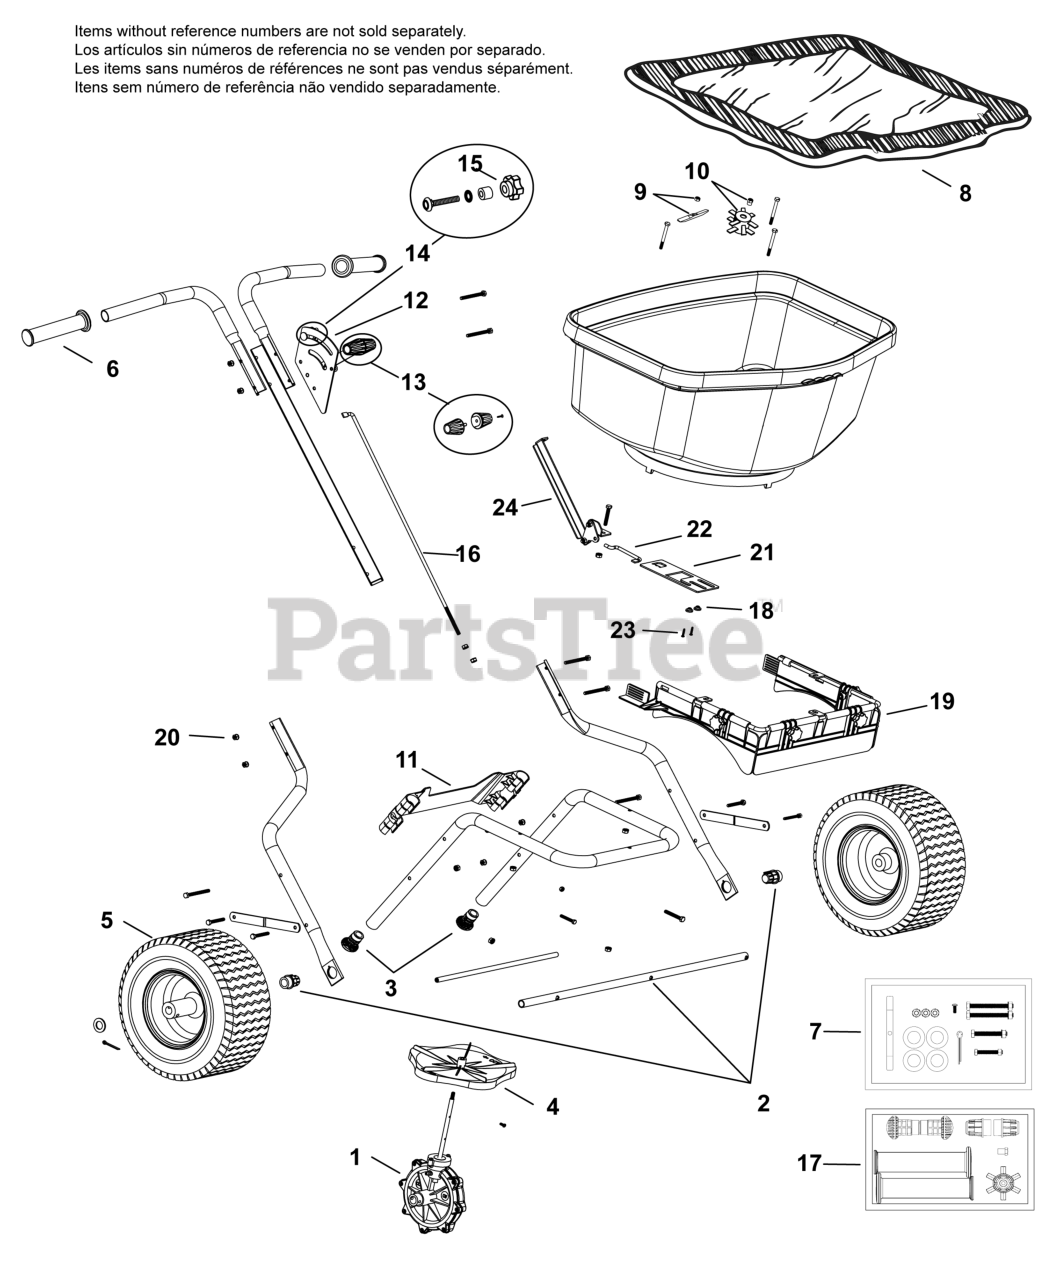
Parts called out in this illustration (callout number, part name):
1	GEAR BOX ASSEMBLY
2	DRIVE SHAFT W/2 BUSHINGS
3	CAP, END
4	IMPELLER & SECURING SCREW ASSEMBLY
5	TIRE & RIM ASSEMBLY 12"
6	HANDLE GRIPS
7	HARDWARE PACK, SS
8	RAIN COVER
9	AUGER & LOCK NUT ASSEMBLY
10	SPIKED AUGER & LOCK NUT ASSEMBLY
11	REAR BAFFLE
12	GATE CONTROL ASSEMBLY, SS
13	KNOB, CONTROL
14	KNOB ASSY
16	ROD, CONTROL LEVER, SS
17	HARDWARE PACK
18	GATE KEEPER
19	BAFFLE ASSY SS
20	LOCK NUT M6 SS
21	SLIDE GATE SS
22	SLIDE LINK SS
23	PLASTITE SCREW #4-20 #1 DRIVE SS
24	LINKAGE ASSEMBLY SS
